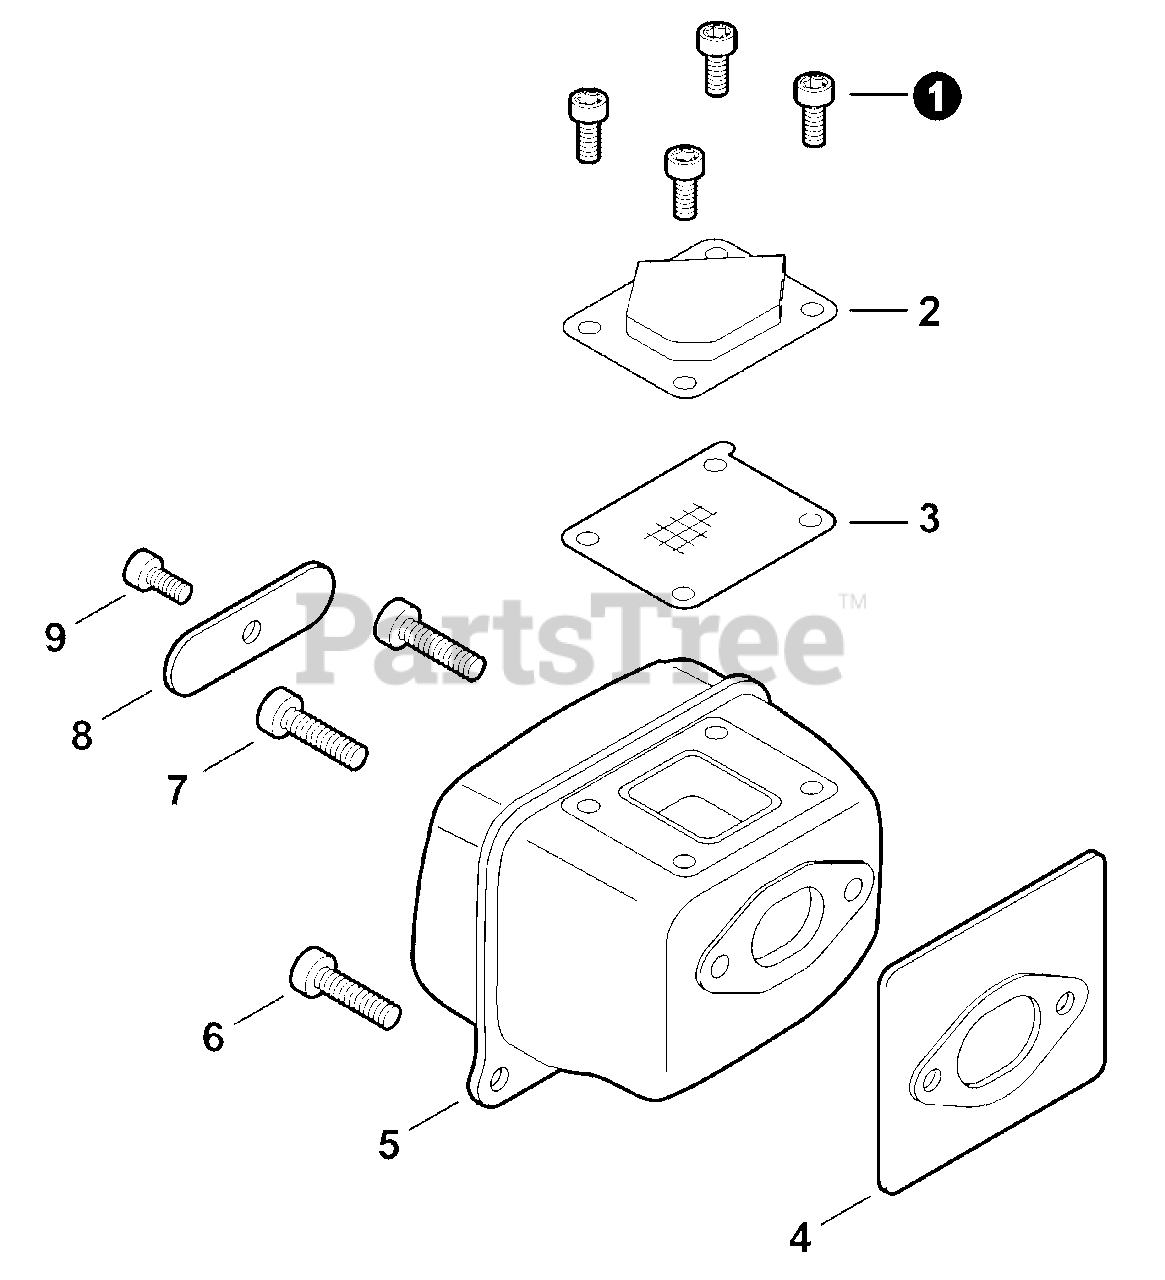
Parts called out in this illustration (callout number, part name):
1	BOLT, TORX 4×8
2	GUIDE, EXHAUST
3	SCREEN, SPARK ARRESTER
4	GASKET, EXHAUST
5	MUFFLER
6	BOLT, TORX 5×20
7	BOLT, TORX 5×20
8	PLATE, MUFFLER
9	BOLT, TORX 4×8
